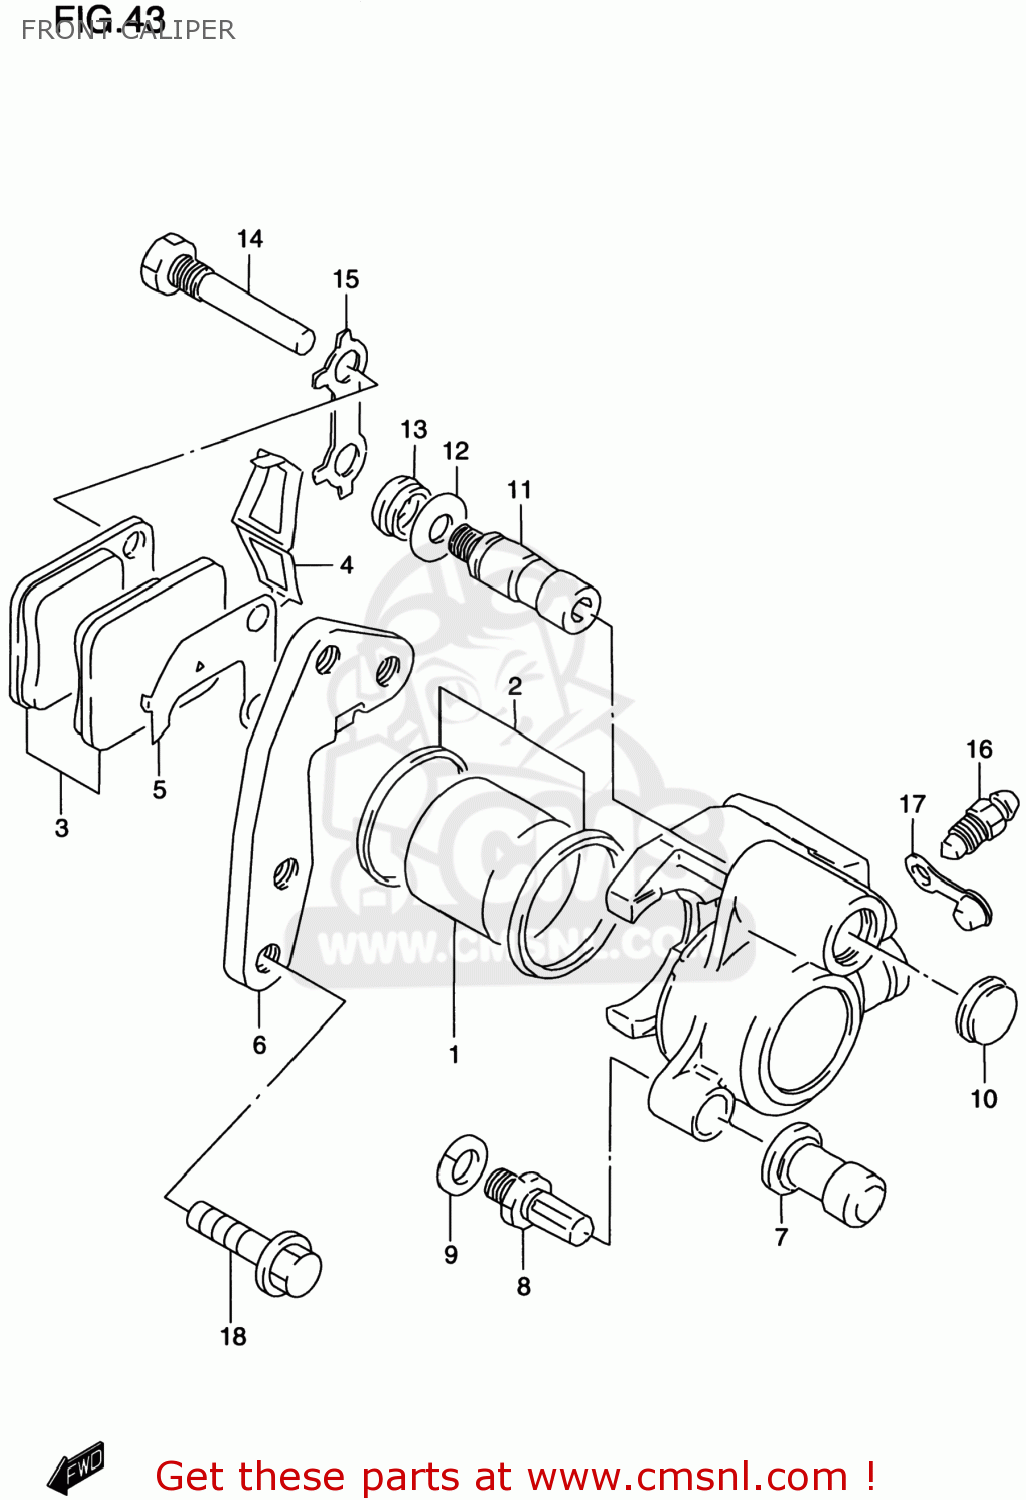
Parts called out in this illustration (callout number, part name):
1	PISTON SET,CALIPERS
2	SEAL SET,PISTON
3	PAD SET (NAS)
4	SPRING,PAD
5	SHIM
6	BRACKET
7	BOOT
8	BOLT,PIN
9	WASHER,WAVE
10	DUST SEAL
11	PIN,SLIDE
12	SPRING,FRICTION
13	BOOT,PIN
14	PIN,HANGER
15	WASHER
16	BLEEDER
17	CAP,BLEEDER
18	BOLT(8X30)
